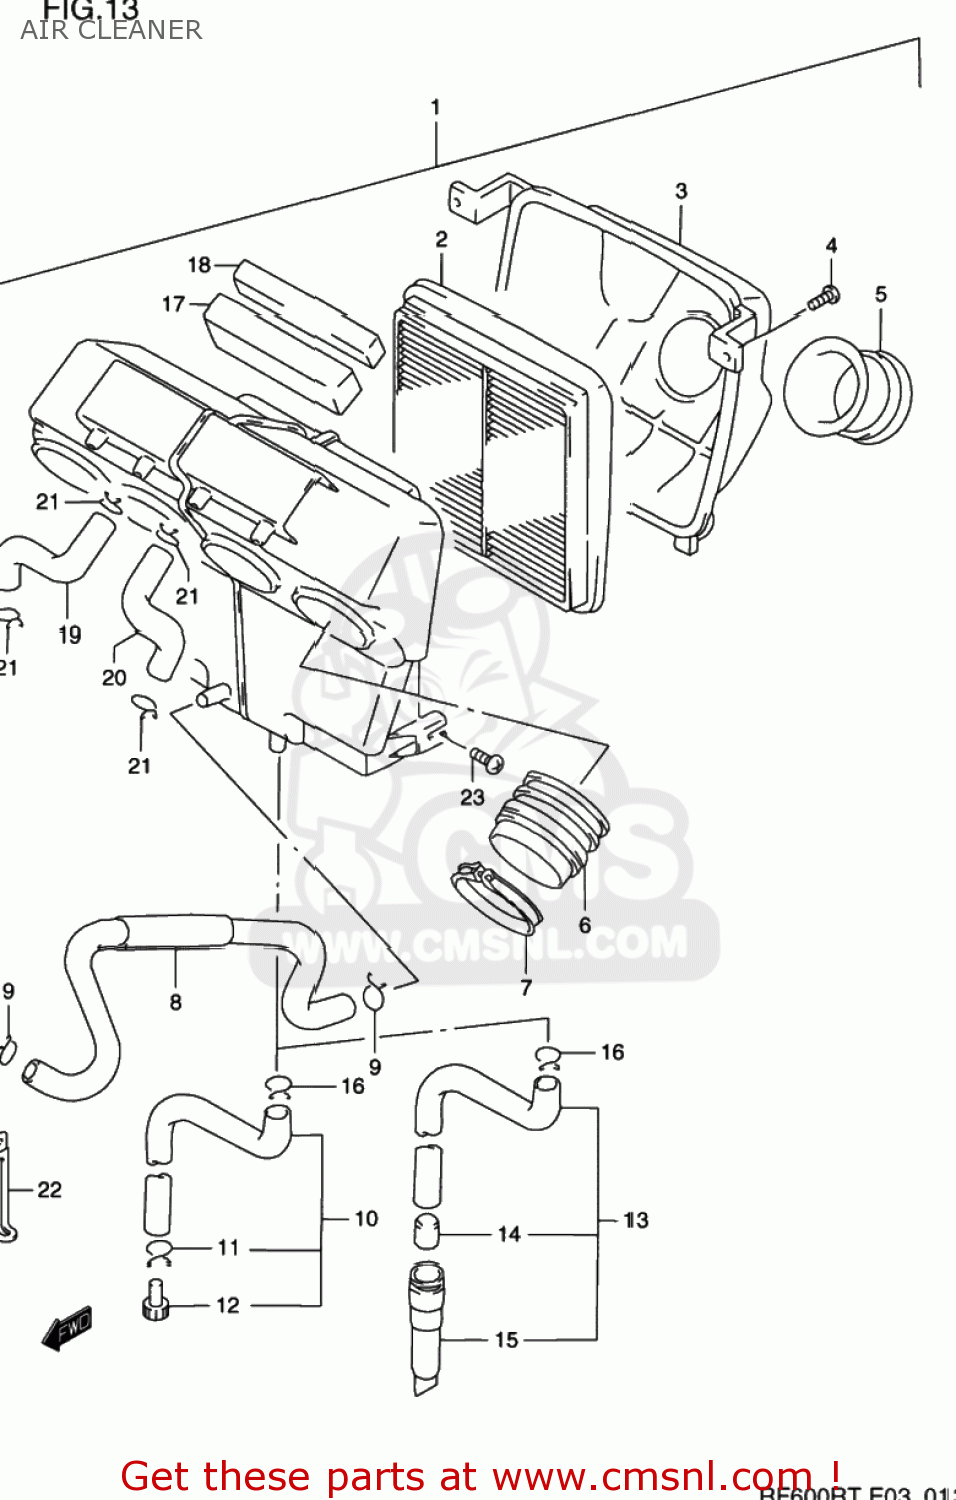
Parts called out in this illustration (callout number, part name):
1	CLEANER ASSEMBLY,AIR
2	FILTER,AIR
3	CAP,AIR CLEANER
4	SCREW
5	TUBE,INLET
6	TUBE,OUTLET
7	CLAMP
8	TUBE,BREATHER
9	CLIP
10	DRAIN TUBE
11	CLIP
12	STOPPER,DRAIN
13	TUBE,DRAIN
14	FILTER,DRAIN
15	CAP,TUB DRAIN
16	CLIP
17	FILTER,CARB AIR
18	FILTER,AIR NO.2
19	TUBE,CARBURETOR AIR,R
20	TUBE,CARBURETOR AIR,LEFT
21	CLIP
22	CLAMP
23	SCREW 6X12
